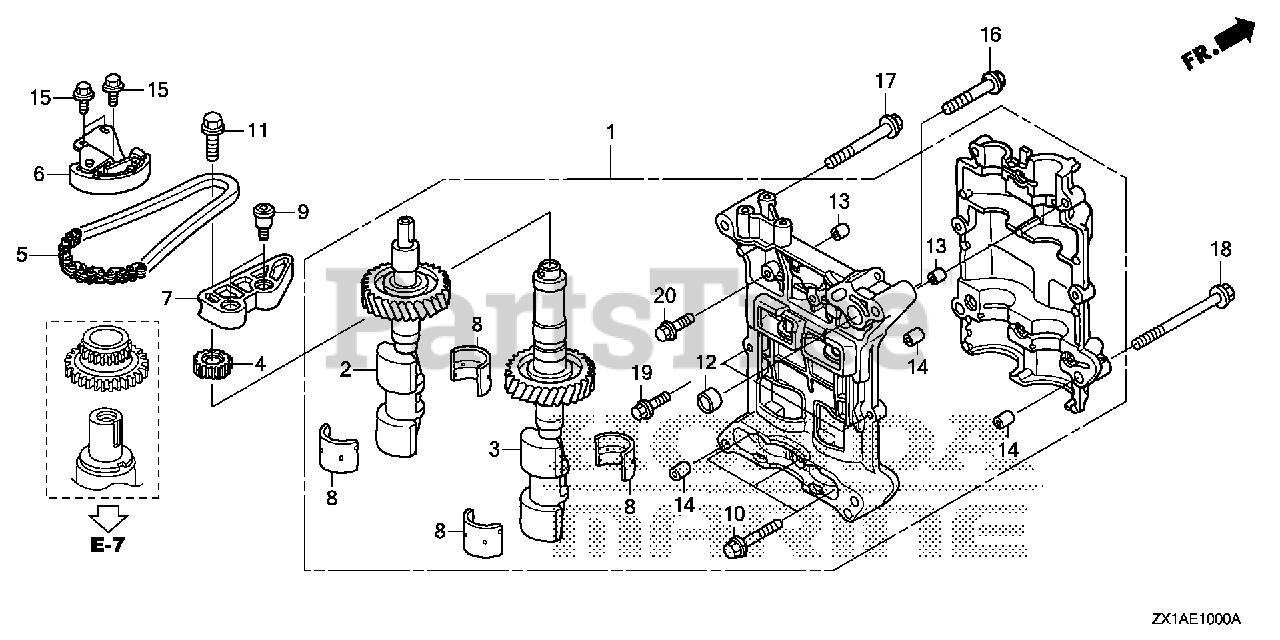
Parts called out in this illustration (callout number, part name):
1	CASE ASSY., BALANCER HOLDER
2	SHAFT, FR. BALANCER
3	SHAFT, RR. BALANCER
4	SPROCKET, DRIVEN (17T)
5	CHAIN (62L)
6	TENSIONER, BALANCER SHAFT CHAIN
7	GUIDE, BALANCER SHAFT CHAIN
8	METAL, BALANCER SHAFT (DAIDO)
9	BOLT, CHAIN GUIDE
10	BOLT, FLANGE (8X55)
11	BOLT-WASHER (10X30)
12	PIN, DOWEL (18X13)
13	PIN A, DOWEL (8X10)
14	PIN A, DOWEL (12X16)
15	BOLT, FLANGE (6X14)
16	BOLT, FLANGE (8X50)
17	BOLT, FLANGE (8X75)
18	BOLT, FLANGE (10X105)
19	BOLT, FLANGE (6X25)
20	BOLT, FLANGE (6X32)
